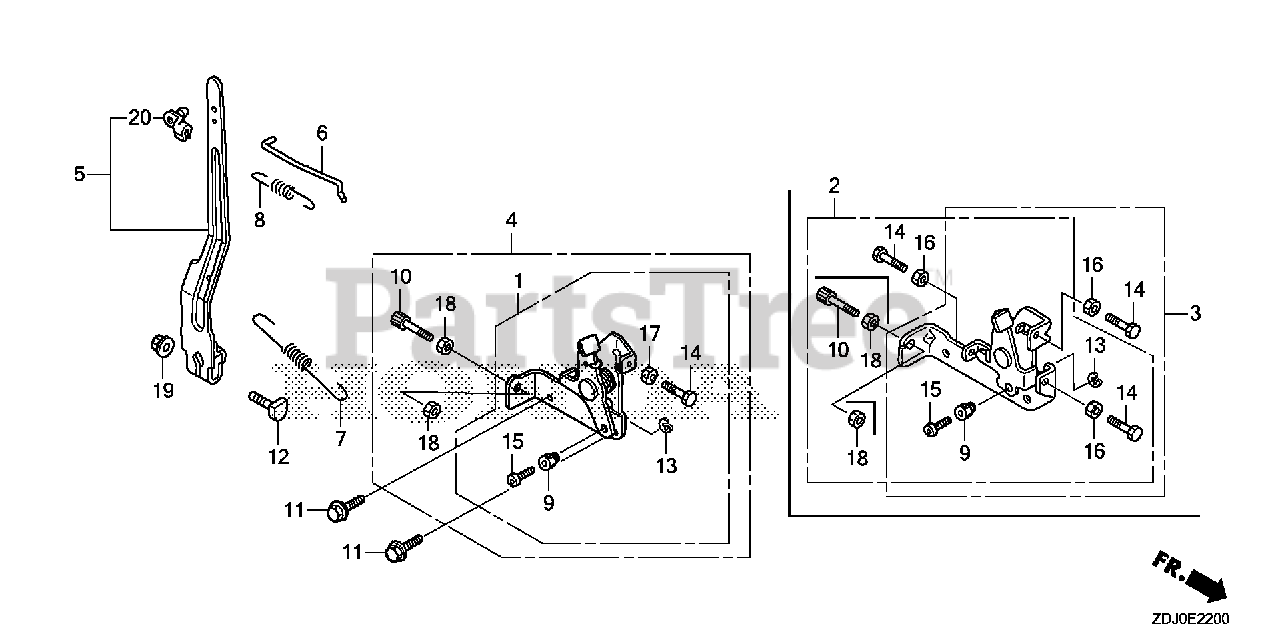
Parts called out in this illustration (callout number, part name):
2	CONTROL ASSY.
5	ARM, GOVERNOR
6	ROD, GOVERNOR
7	SPRING, GOVERNOR
8	SPRING, THROTTLE RETURN
9	HOLDER, WIRE
11	BOLT, FLANGE (6X14)
12	BOLT, GOVERNOR ARM
13	CIRCLIP (5MM) Use from Engine SN 2327377.
14	BOLT, HEX. (5X20)
15	SCREW, PAN (4X6)
16	NUT, HEX. (5MM)
19	NUT, FLANGE (6MM)
20	JOINT, ROD
